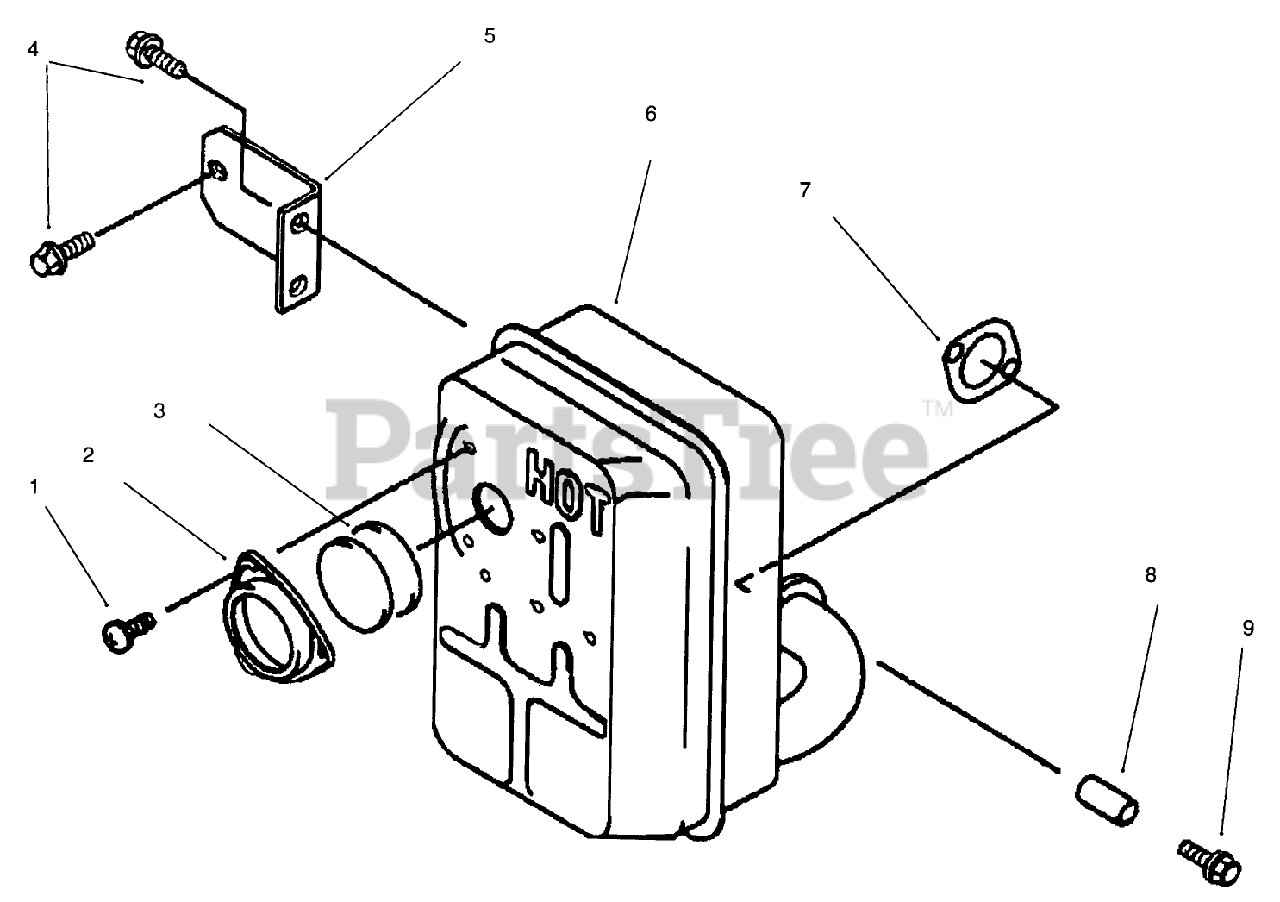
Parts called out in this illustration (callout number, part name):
1	Screw
2	Cap
3	Arrester-Spark
4	Bolt-Flanged (8X12)
5	Bracket
6	Muffler Assembly (Incl. Ref. #1-3)
7	Gasket-Muffler
8	Collar
9	Bolt-Flanged (8X45)
